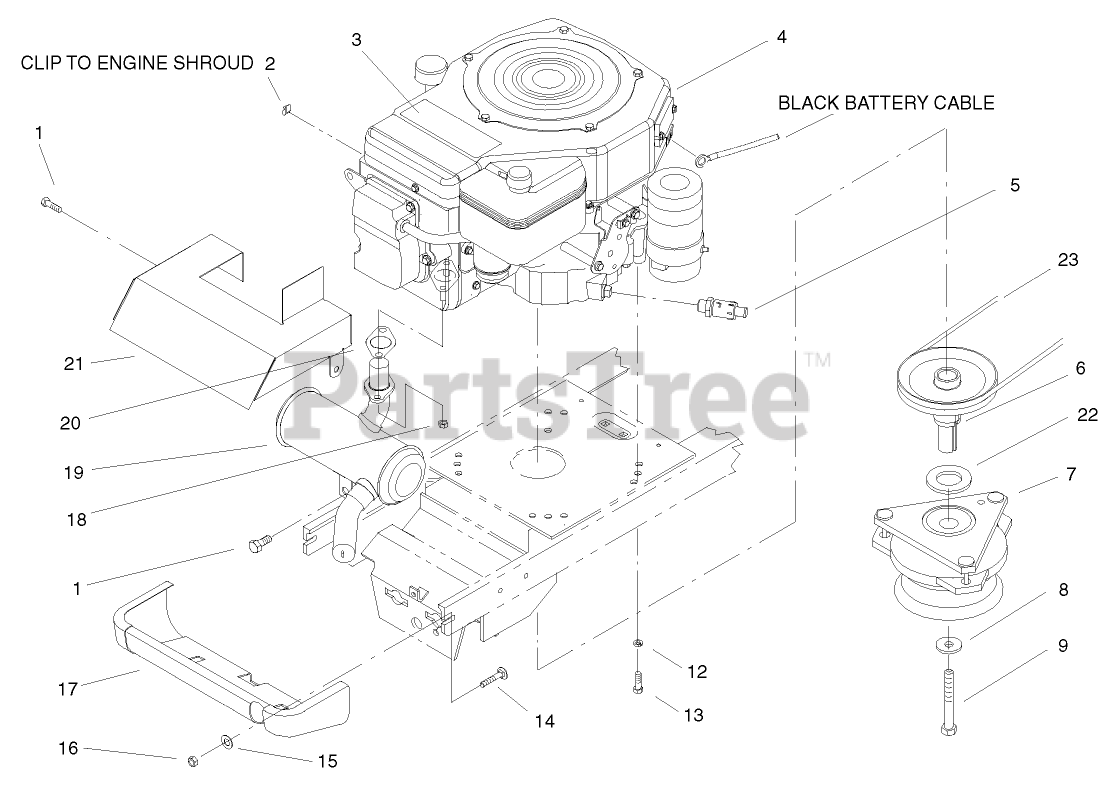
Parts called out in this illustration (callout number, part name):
1	SCREW-HWHTF
2	CLIP-RETAINER, WIRE
4	Engine-Kohler(Only On: 70264)
5	VALVE-DRAIN, OIL
6	PULLEY-ENGINE
7	CLUTCH-ELEC PTO
8	WASHER
9	SCREW-HH
12	WASHER-LOCK
13	SCREW-HH
14	BOLT-CARR
15	WASHER-FLAT
16	NUT-LOCK, NI
19	MUFFLER
20	KOHLER 12-041-03
21	SHIELD-MUFFLER
22	SPACER-CLUTCH
23	V-BELT
